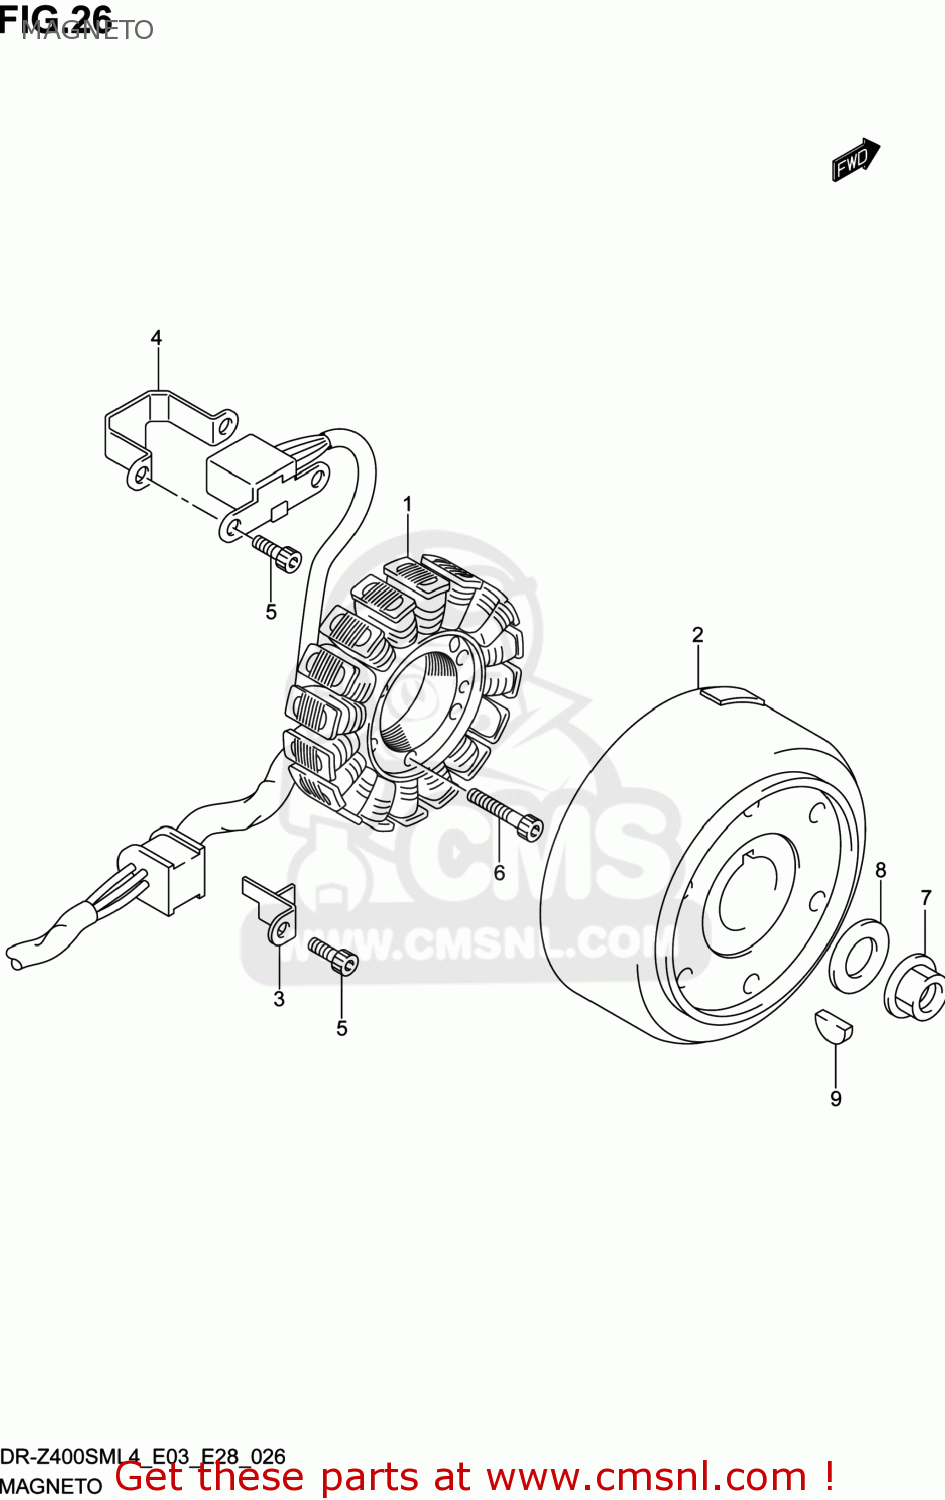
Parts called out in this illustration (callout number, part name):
1	STARTER ASSY
2	ROTOR ASSY
3	CLAMP,MAGNETO LEAD NO.1
4	CLAMP,MAGNETO LEAD WIRE
5	BOLT
6	BOLT
7	NUT
8	WASHER(12X27X2)
9	KEY
